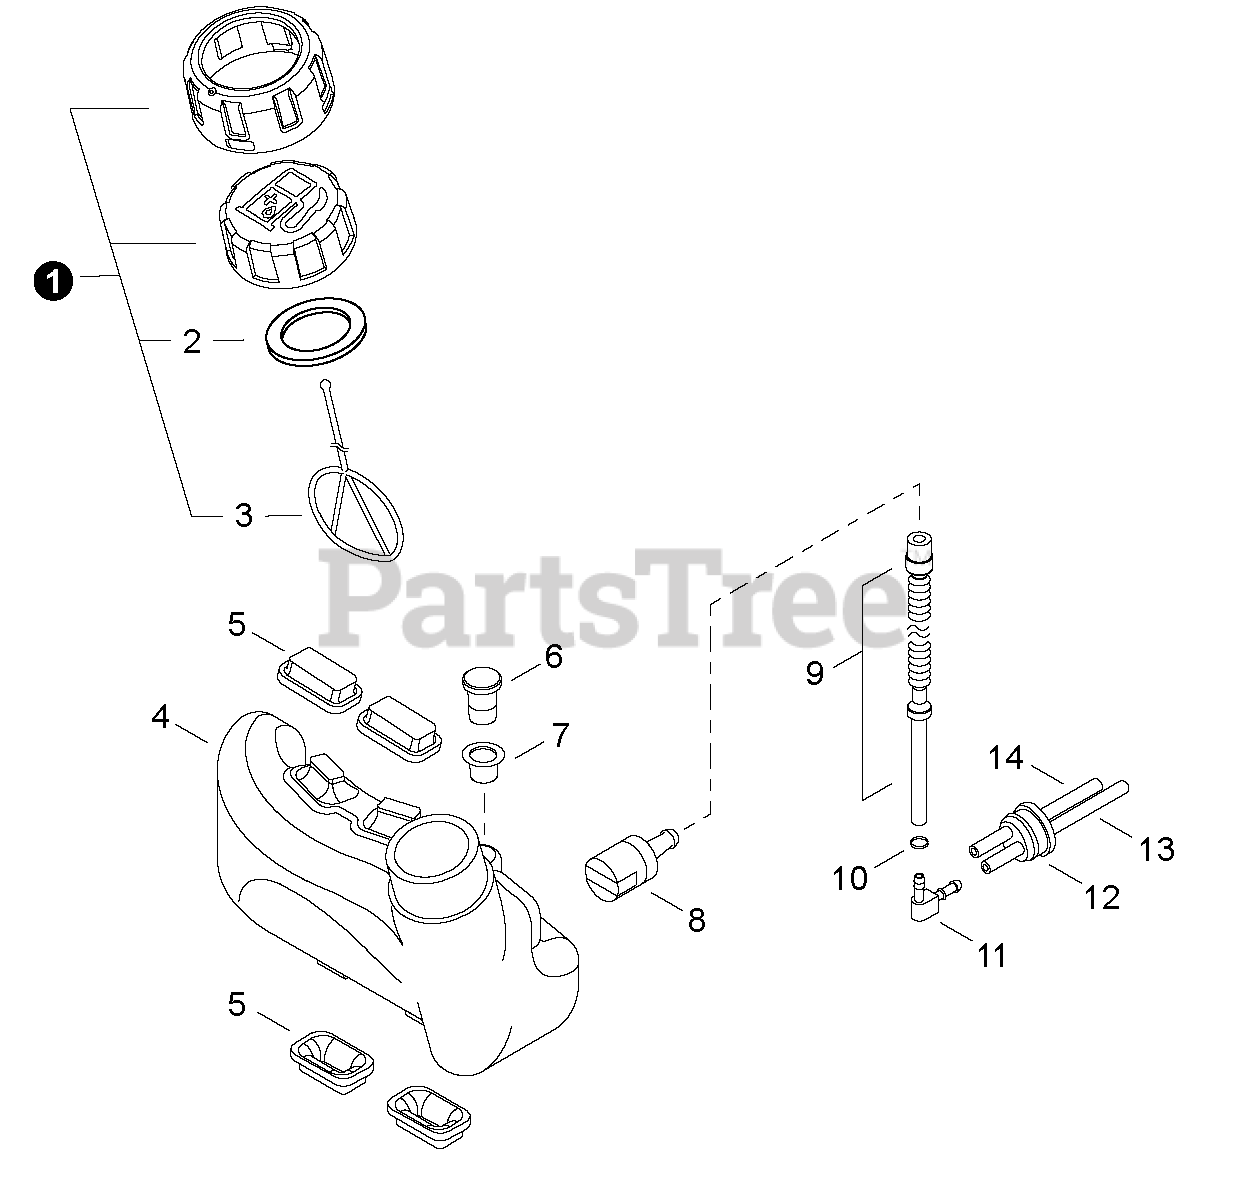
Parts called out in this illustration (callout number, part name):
1	CAP ASSY
2	GASKET, CAP
3	CONNECTOR, CAP
4	TANK, FUEL
5	CUSHION
6	VENT, FUEL TANK
7	GROMMET
8	FILTER, FUEL
9	PIPE - FUEL
10	CLIP - 6.5
11	CONNECTOR, PIPE
12	GROMMET
13	PIPE - 3X5X83 -- BLACK
14	PIPE - 3X6X85 -- CLEAR
